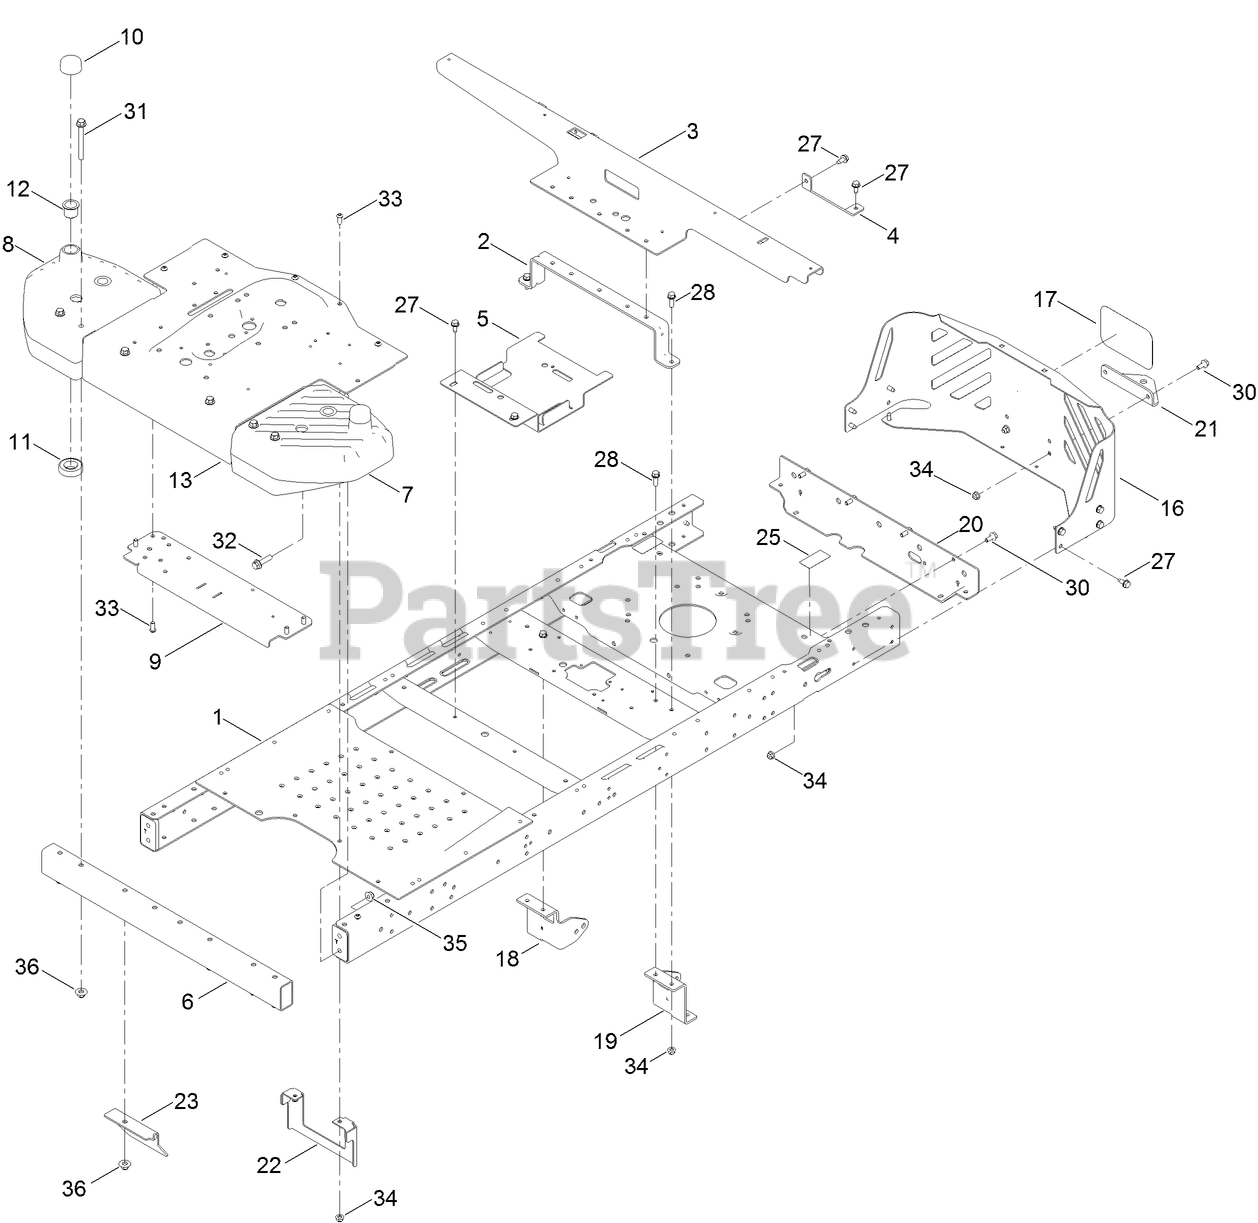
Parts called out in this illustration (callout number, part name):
1	FRAME ASM (WIDE)
2	BRACE-SEAT, REAR (WIDE)
3	SUPPORT-POD, WIDE
4	SUPPORT-TANK, REAR
5	BRACKET-BATTERY
6	TUBE-FRONT, WIDE
7	HOUSING-SPINDLE, LH
8	HOUSING-SPINDLE, RH
9	PLATE-BRIDGE, WIDE
10	CAP-CASTER
11	BEARING-BALL
12	BUSHING-PIVOT
13	PAN-STEER, FRONT
16	GUARD-ENGINE, WIDE
17	DECAL
18	MOUNT-HYDRO, FRONT (RIGHT)
19	MOUNT-HYDRO, FRONT (LEFT)
20	CROSSMEMBER-REAR, WIDE
21	BRACKET-HITCH
22	BRACKET-UPSTOP
23	GUARD-FRONT
25	DECAL-BYPASS
27	SCREW-HWHTF
28	SCREW-HHF
30	SCREW-HHF
31	SCREW-HHF
32	SCREW-HHF
33	SCREW-HSBH
34	NUT-HF, NI
35	NUT-HF, NI
36	NUT-FLANGE, NI
